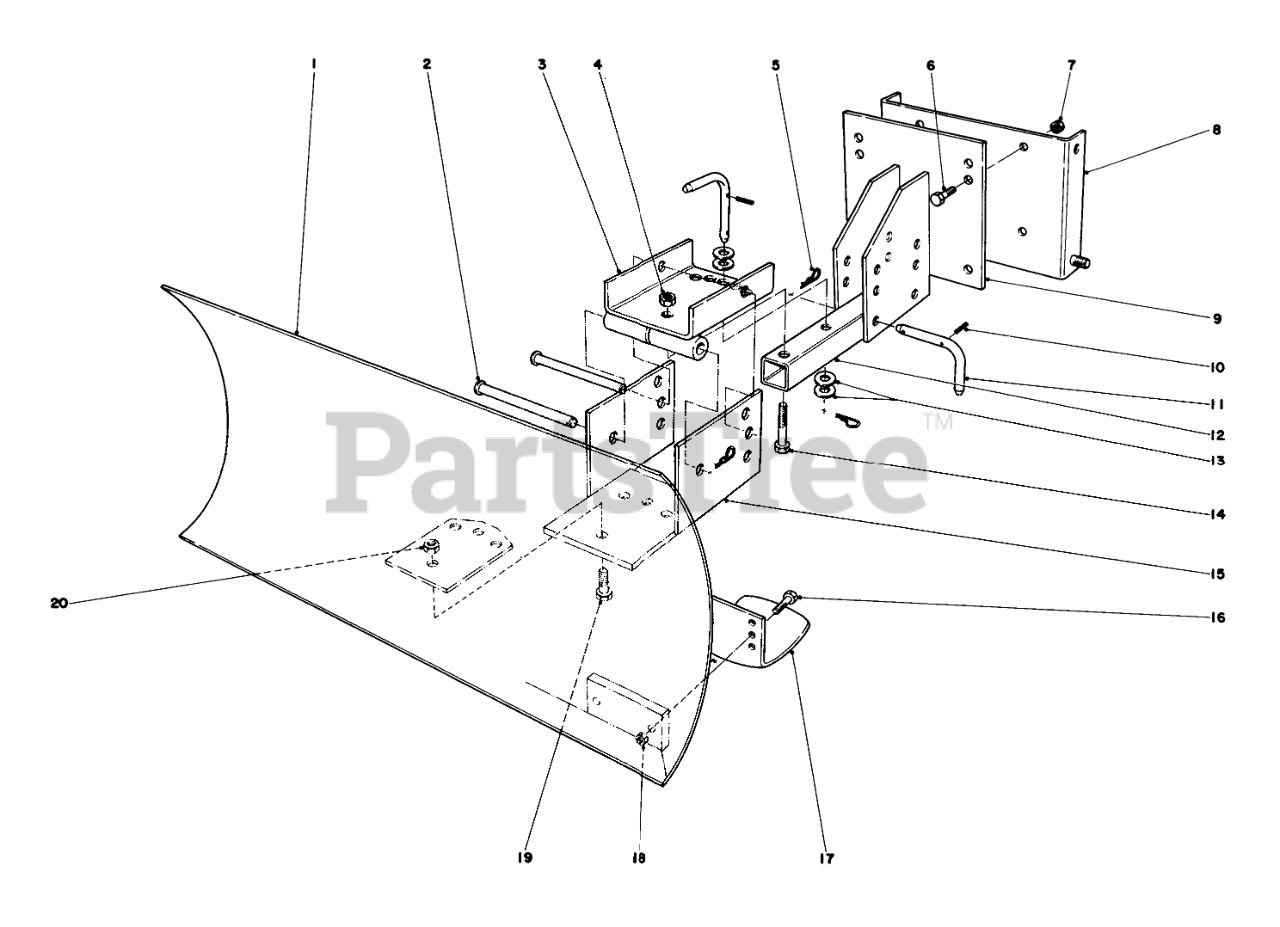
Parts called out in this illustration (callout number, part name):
1	Blade
2	PIN-CLEVIS
3	Swivel Bracket
4	1/2-13 CONELOCK NUT
5	PIN-HAIR
6	SCREW-HH
7	NUT-LOCK, CONE
8	Mounting Plate (Used with 826 & 1132 Units only)
9	Mounting Plate
10	PIN-SPRING
11	Pivot Pin
12	Blade Tongue
13	WASHER-FLAT
14	SCREW-HH
15	Blade Adjustment
16	SCREW-HH
18	NUT-LOCK, CONE
19	SCREW-HH
20	1/2-13 CONELOCK NUT
